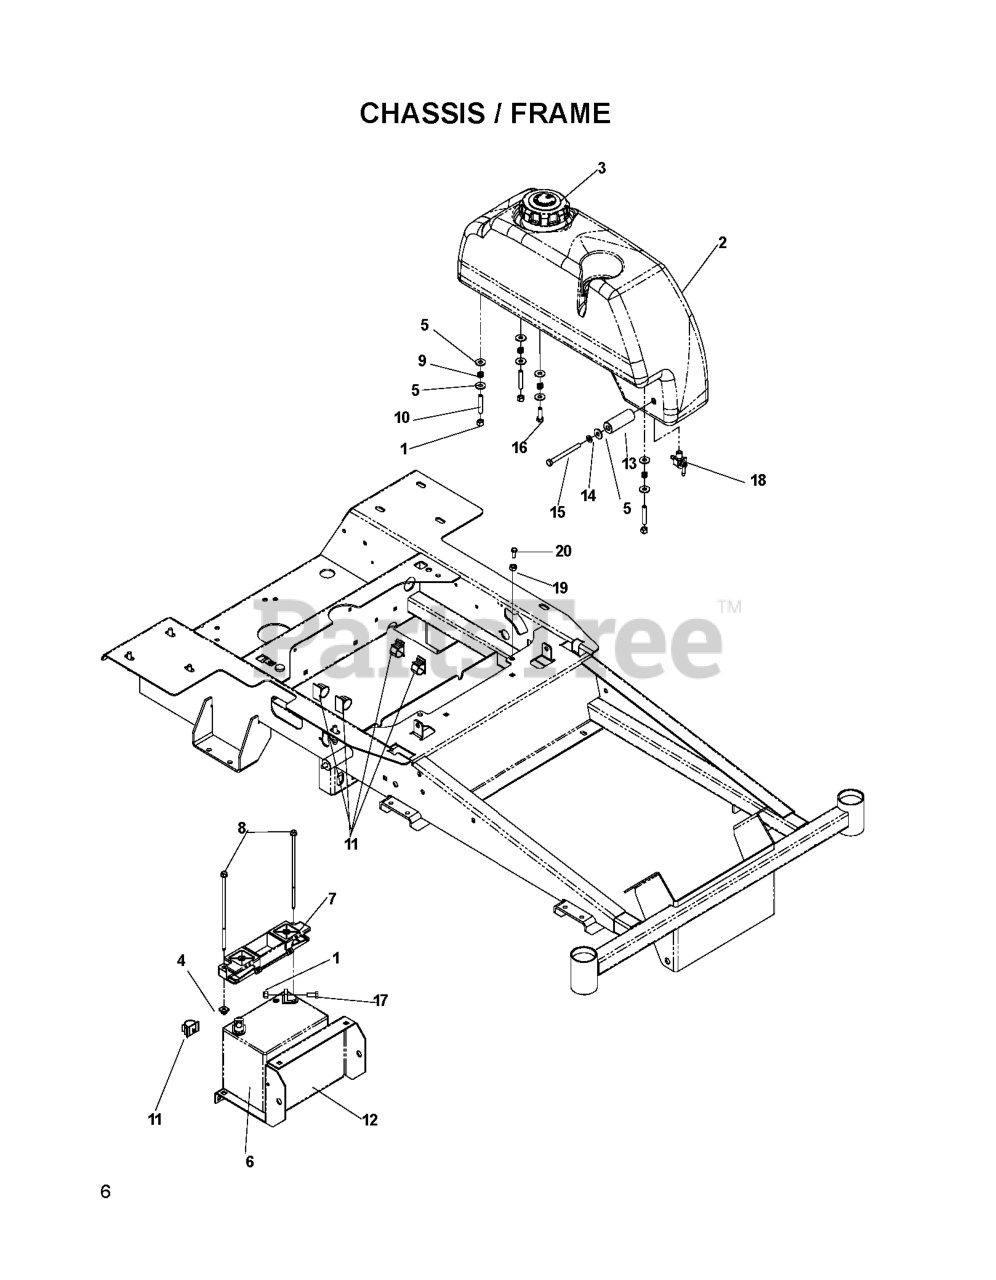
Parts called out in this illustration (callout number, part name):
1	NUT 5/16 NYLOC
2	LEFT TANK W/CUP HOLDER
3	FUEL CAP ANTI-SPLASH
4	PUSH NUT-NYLON
5	WASHER 5/16 FLAT
6	BATTERY, 12 V 330 AMP
7	BATTERY HOLD DOWN
8	BOLT - 1/4-20 X 7.5
10	STUD, 5/16C
11	PUSH-MOUNT WIRE CLIP
12	BATTERY TRAY
13	TANK SPACER
14	WASHER.LOCK.HVY.HLCL.SPR.5/16
15	BOLT - HCS 5/16C X 3.5
16	HCS 5/16C X 1
17	HCS 5/16C X 3/4
18	FUEL VALVE
19	NUT 5/16C HEX
20	HCS 5/16-18X1-3/4 TPBLT
